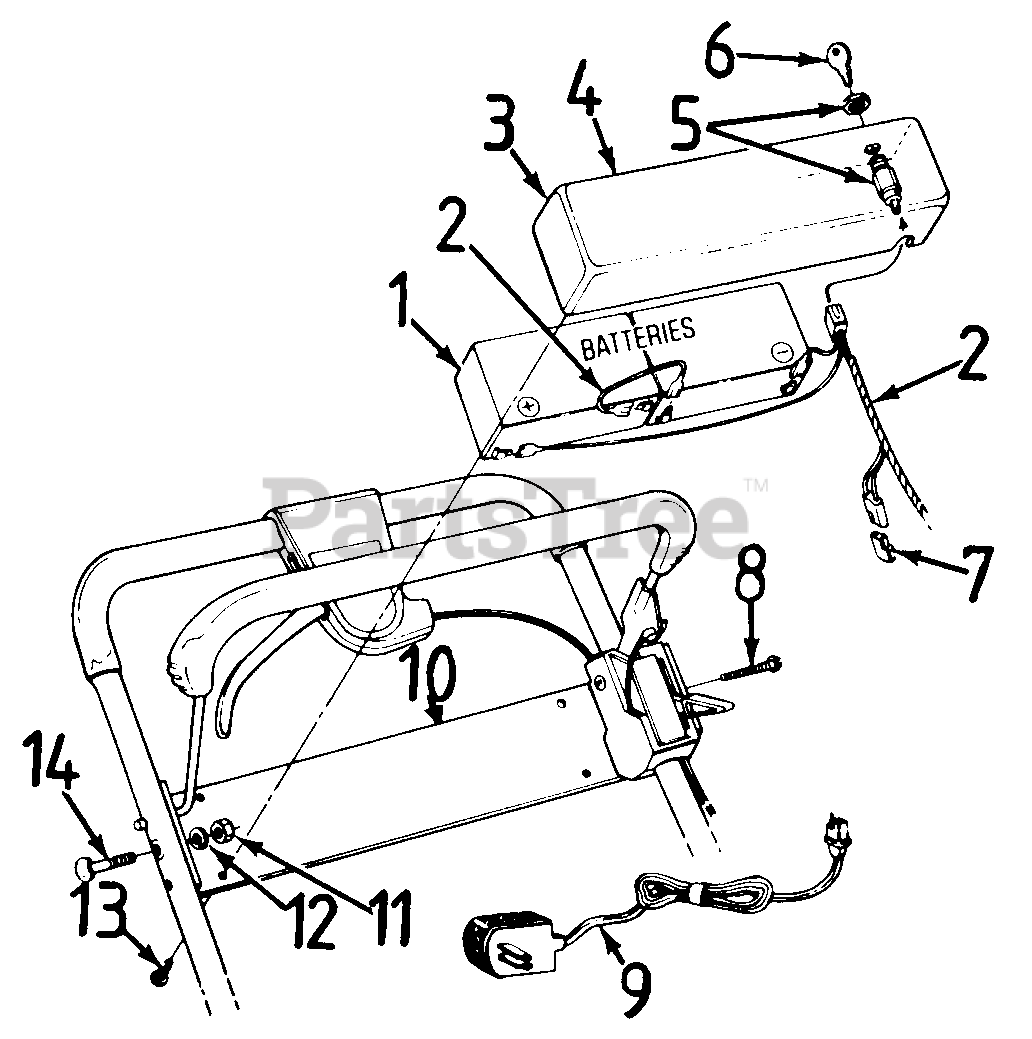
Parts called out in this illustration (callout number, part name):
1	Battery Pack
2	Wire Harness
3	Battery Tray
4	Instruction Label
5	Ignition Switch
6	Ignition Key
7	Plug
8	Truss Mach. Scr. #12 x 1.5" Lg.
9	Battery Charger
10	Lower Battery Tray
11	Hex Nut 5/16-18 Thd.
12	L-Wash. 5/16" I.D.
13	Truss Mach. H-Riser Tap Scr. 1 " Lg.
14	Curved Carriage Bolt 5/1 6-1 8 x 1.38" Lg.
